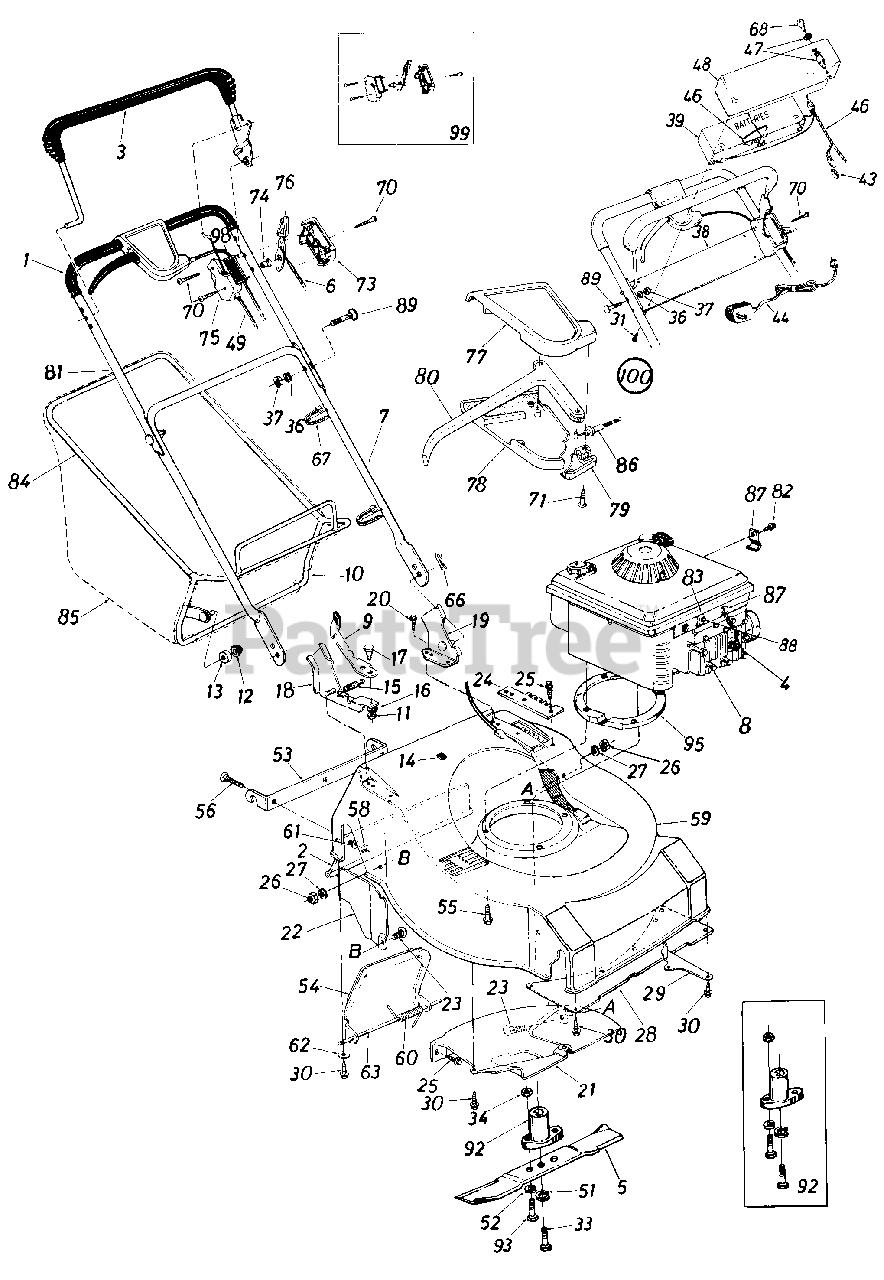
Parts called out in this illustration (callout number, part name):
2	Rear Flap Ass'y.
3	Control Handle-L.H.
4	Spark Plug Insulator
5	22" Blade
6	Throttle Wire-58"
7	Lower Handle (Chrome)
8	Engine
9	Grass Catcher Lock Lever
12	Push Nu 3/8 Rod
13	Plastic Roller
15	Extension Spring
16	L-Wash. 5/16" I.D.*
17	Shld. Bolt .437" Dia. x .162"
18	Handle Brkt. Ass'y.-R.H.
19	Handle Brkt. Ass'y.-L.H.
20	Hex Hd. Self-Tap Scr. 1/4-20 x 1.00" Lg.
21	Rear Baffle-L.H.
22	Side Baffle
23	Carriage Bolt 1/4-20 x .50"
24	Reinforcement Brkt.
25	Hex Wash. Hd. Drill Scr. 1/4 x .75" Lg.
26	Hex Nut 1/4-20 Thd.*
27	L-Wash. 1/4" I.D.*
28	Front Cover Plate
29	Left Strap
30	Hex Wash. Hd. AB-Tap Scr. 1/4 x.62" Lg.
31	Truss Mach. Hi-Riser Tap Scr. 1" Lg.
33	Hex Bolt 3/8-24 x 2.25" Lg. (Grade 5)
34	Hex Nut 5/16-24 Thd.*
36	L-Wash. 5/16" I.D.*
37	Hex Nut 5/16-18 Thd.*
38	Lower Battery Tray
39	Battery Pack
43	Plug
44	Battery Charger
46	Wire Harness
47	Ignition Switch
48	Battery Tray
49	Control Cable-43" L.
51	L-Wash. 3/8" I.D. Heavy Duty
52	L-Wash. 5/16" I.D.
53	Grass Catcher Hitch Brkt.
54	Chute Door
55	Hex Wash. Hd. TT-Tap Scr. 3/8-16 x 1.00" Lg.
56	Carriage Bolt 1/4-20 x .75"
58	Sems Nut 1/4-20 Thd.
59	22" Deck Ass'y.
60	Torsion Spring .34" I.D. x 2.38" Lg.
61	Fl-Wash. .281 " I.D. x .73"
62	Fl-Wash. .285" I.D. x 1.25"
63	Rod .25" Dia. x 8.25" Lg.
66	Intern. Cot. Pin 5/16" Dia.
67	Cable Tie
68	Ignition Key
70	Truss Mach. B-Tap Scr. #12 x 1.50" Lg.
71	Flat C-Sunk AB-Tap Scr. #10 x .75" Lg.
73	Control Panel Half
74	Control Disc Pin
75	Clutch Panel Half
76	Throttle Control Lever
77	Control Cover Half-Upper
78	Control Cover Half-Lower
79	Cable Mtg. Cap
80	Control Lever
81	Upper Handle (Chrome)
82	Hex B-Tap Scr. #10 x .38
83	Casing Clamp
84	Grass Catcher Upper Frame
85	Grass Bag
86	Drive Clutch Cable-50"
87	Casing Clamp
88	Hex B-Tap Scr. #10 x .62"
89	Curved Carriage Bolt 5/16-18 x 1.38" Lg.
92	Blade Adapter Kit
93	Hex Bolt 5/16-24 x 1.00" Lg. (Grade 5)
95	Engine Mounting Cover Plate
99	Kit-Control Housing Comp.
100	Kit-Clutch Control Housing Comp.
